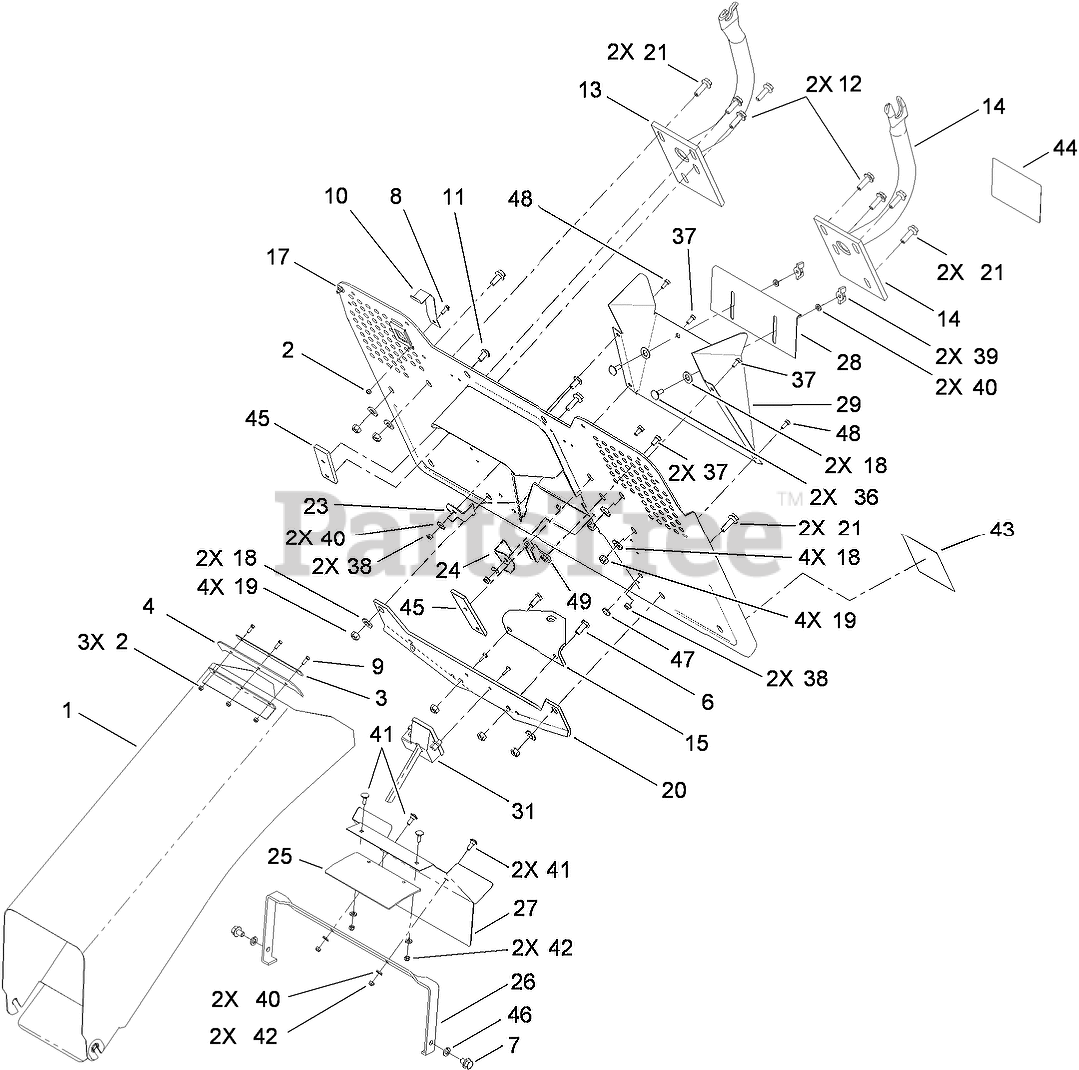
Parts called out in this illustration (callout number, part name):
1	Tunnel
2	NUT-HEX
3	PLATE-SUPPORT
4	SEAL-RUBBER
6	SCREW-HH
7	SCREW-HHF
9	SCREW-SFH
10	BRACKET-BAG PRESENT SWITCH
11	BOLT-CARRIAGE
13	SUPPORT-COLLECTOR, RIGHT
14	SUPPORT-COLLECTOR, LEFT
15	HITCH-TOW
17	COLLECTOR PLATE ASM
18	WASHER-FLAT
19	NUT-LOCK, NI
20	SUPPORT-HITCH, TOW
21	SCREW-HEX
23	Support-Tunnel, Left
24	Support-Tunnel, Right
25	Shield-Rubber
26	BRACKET-SHIELD, PROTECTIVE
27	SHIELD-PROTECTIVE
28	Shield-Adjustable
29	Hopper-Receiving
31	OVERLOAD SWITCH ASM
37	SCREW-HH
38	NUT-LOCK
39	NUT-WING
40	WASHER-FLAT
41	BOLT-CARRIAGE
42	NUT-LOCK
43	DECAL-BYPASS, HYDRO
44	DECAL-POSITION, BAGGING
45	Plate-Reinforcing
46	Washer-Spring
47	Bushing
48	Screw-HH
49	BRACKET-SUPPORT, FUEL TANK
